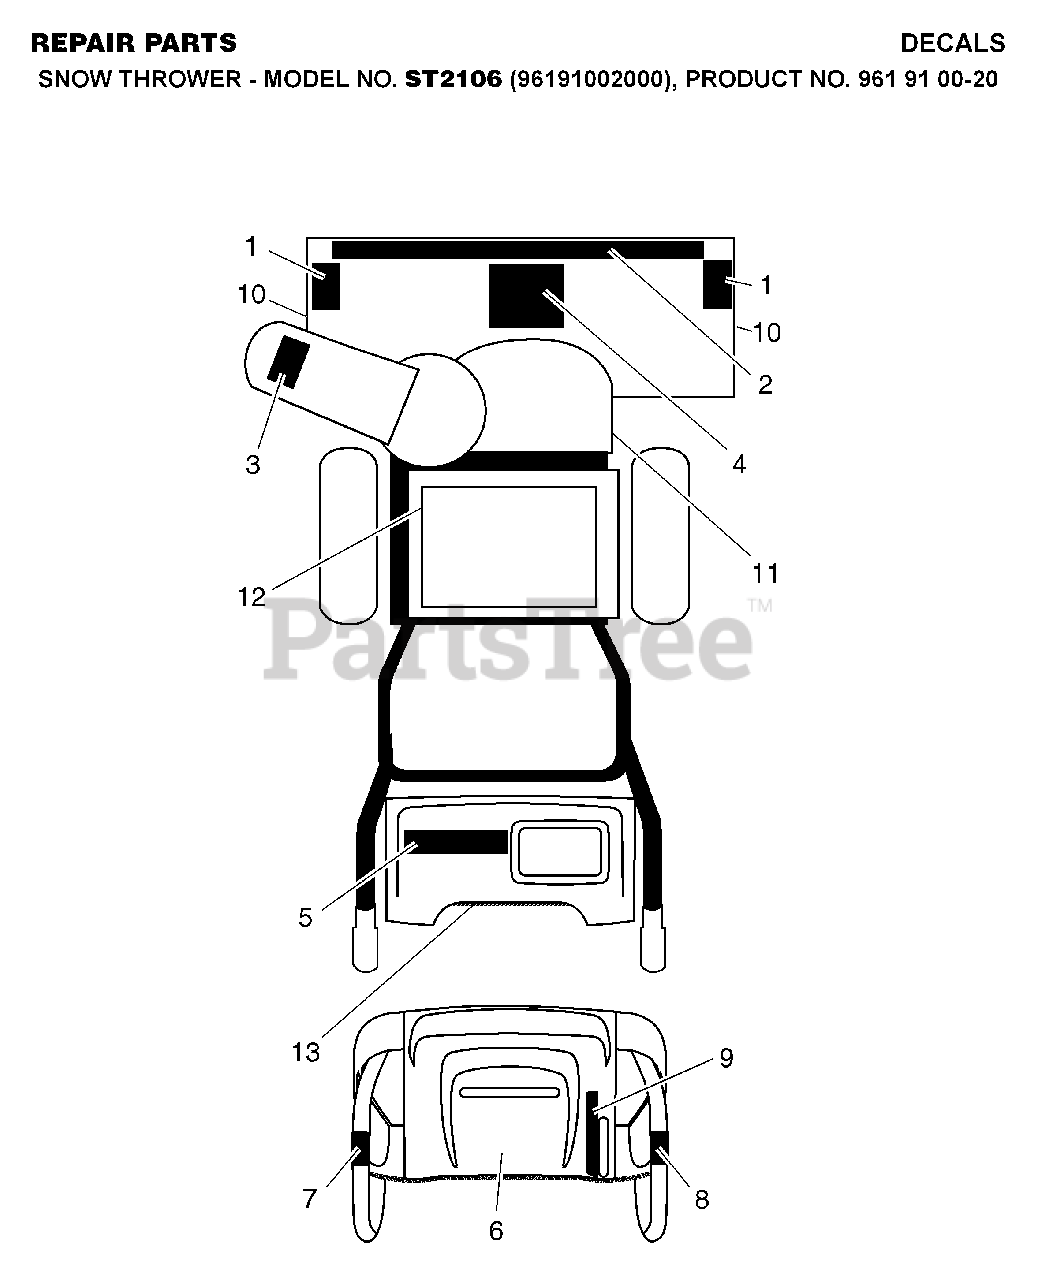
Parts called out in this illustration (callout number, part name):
1	DECAL.AUGER.SAFETY.
3	DECAL.CHUTE.SAFETY.
4	DECAL.AUGER."
6	DECAL.CONSOLE.INSTRUCTION
11	DECAL.BELT.GUARD.
